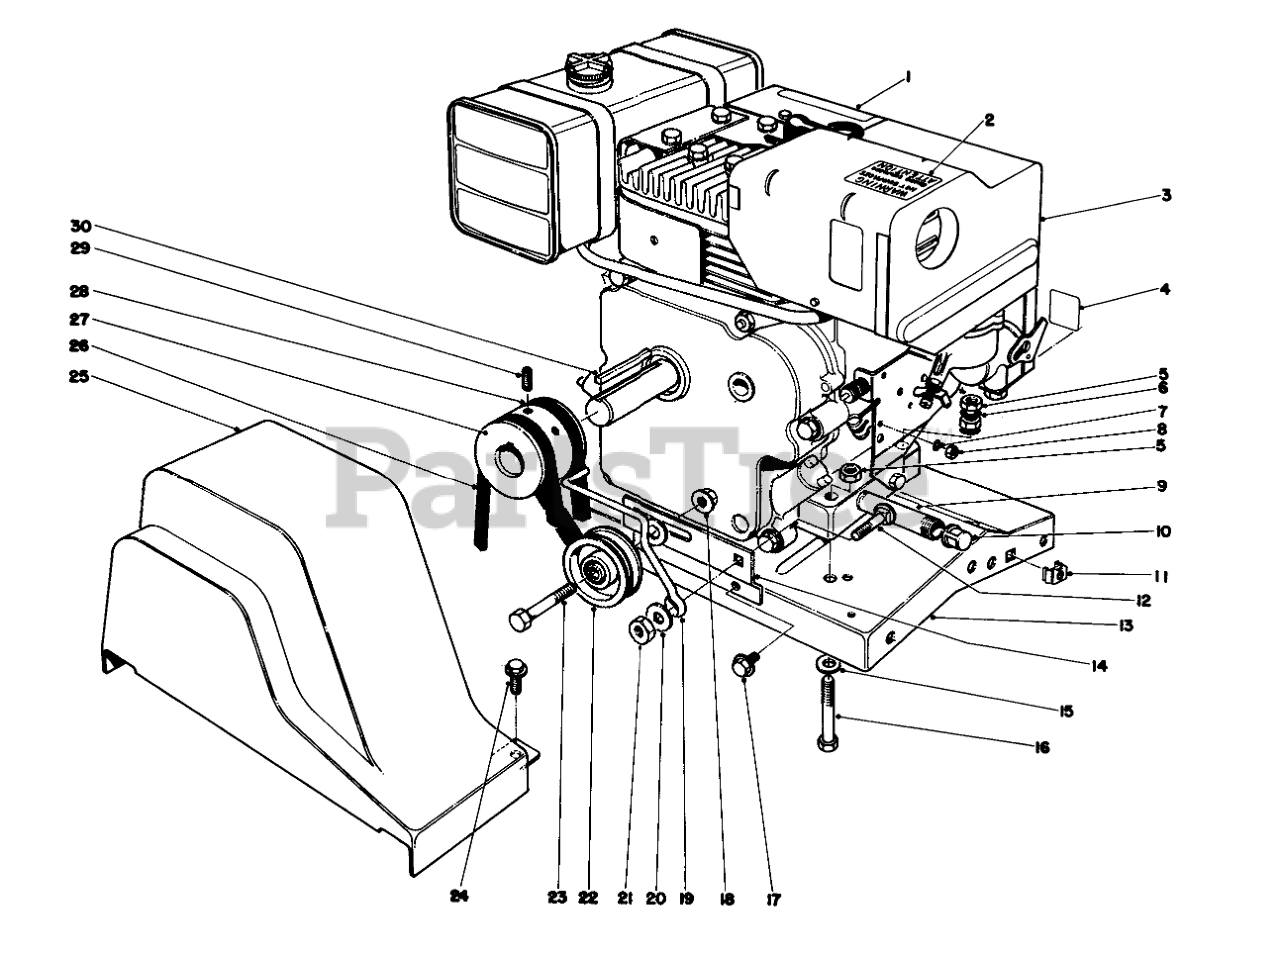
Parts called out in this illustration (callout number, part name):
1	CAUTION DECAL
2	Decal Hot Surface Warning
3	Engine
4	CHOKE DECAL
5	NUT-LOCK, NI
6	WASHER-LOCK, INTERNAL
7	WASHER-LOCK/INT
8	NUT-LOCK
9	NIPPLE-PIPE
10	Pipe Cap
11	Retained Nut
12	SCREW-CARR
13	Base-Engine
14	Belt Idler Bracket
15	WASHER-PLAIN
16	SCREW-HH
17	SCREW-HHFTF
18	NUT-HHF, WHIZ
19	BELT GUIDE
20	WASHER-FLAT
21	NUT-HEX
22	PULLEY B
23	SCREW-HH
24	SCREW-HWH
25	BELT GUARD
26	V-BELT
27	Pulley
28	V-BELT
29	Screw-Set
